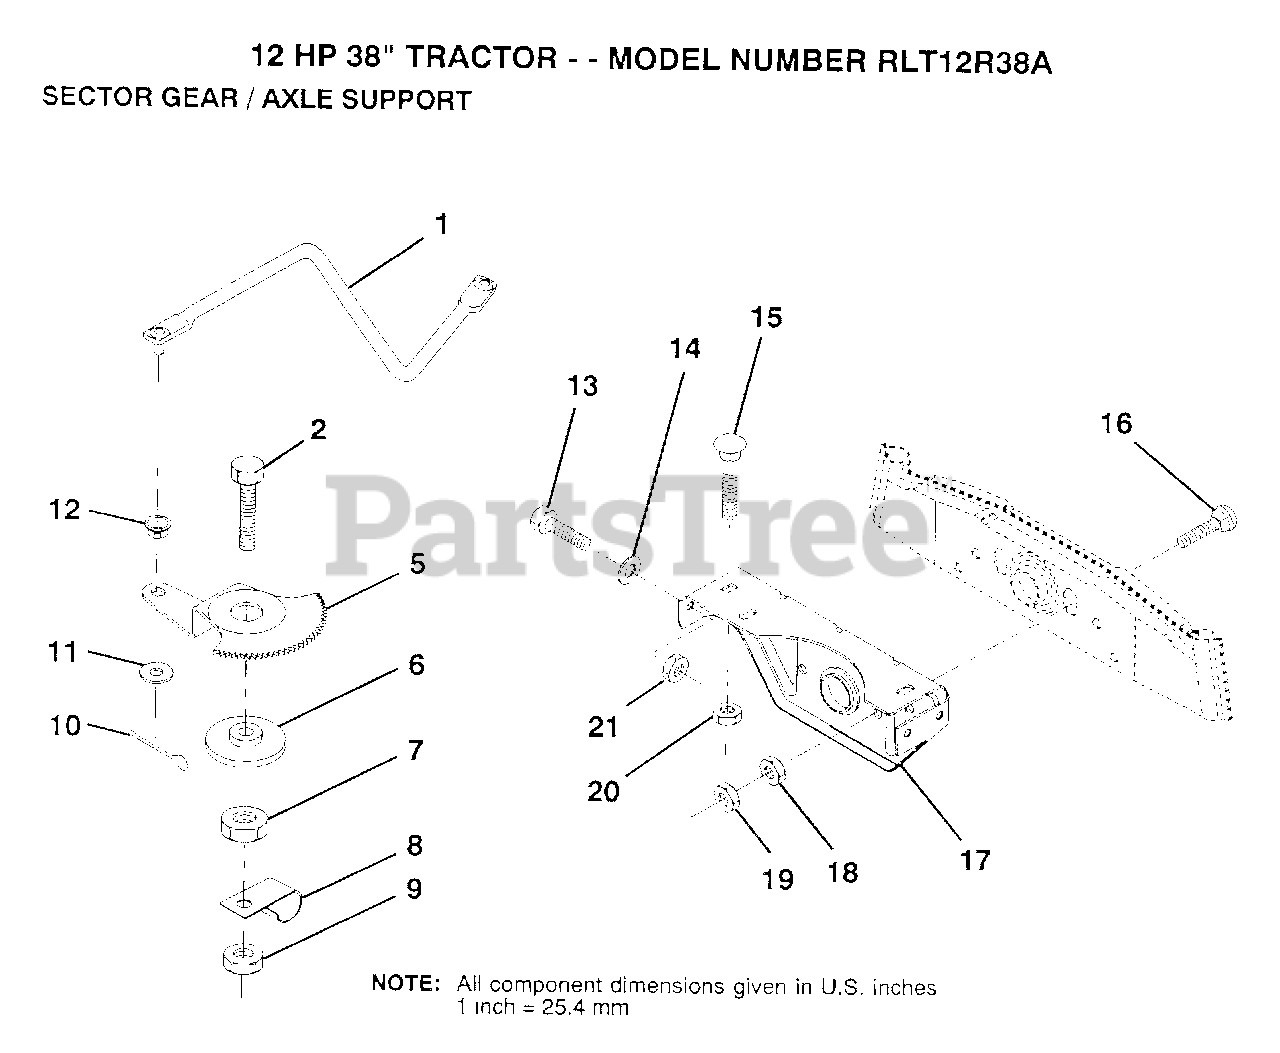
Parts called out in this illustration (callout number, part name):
1	DRAG LINK
2	"BOLT,HEX"
5	GEAR SECTOR
6	BUSHING
7	NUT
8	CLIP INSULATOR
9	NUT LTV
10	COTTER PIN
11	WASHER
12	BUSHING.DRAGLINK
13	BOLT
14	WASHER
15	BOLT
16	BOLT
17	"SUPT,FRT AXLE"
18	NUT.HEX.3/8-16UNC
19	LOCKNUT
